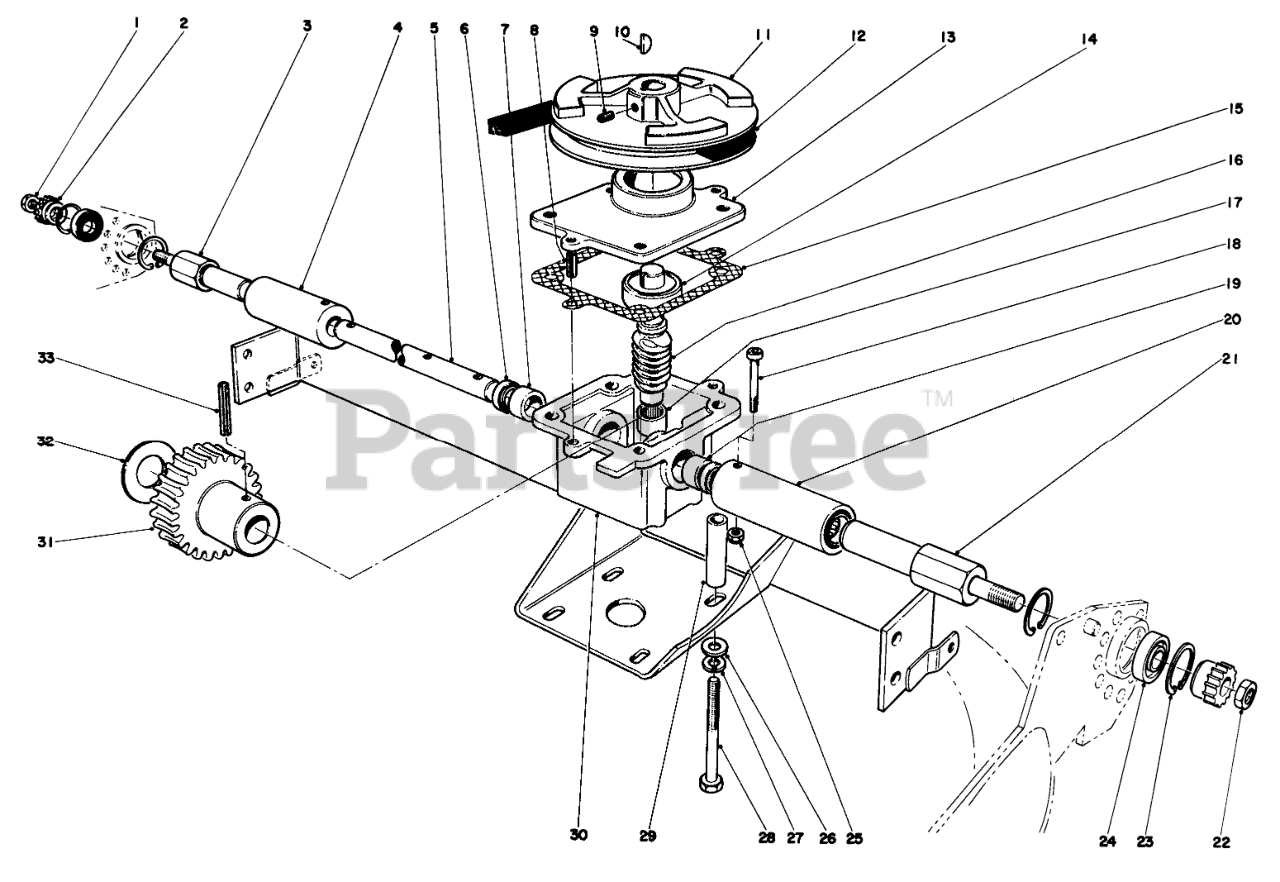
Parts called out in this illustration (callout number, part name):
1	NUT-HJ
2	Pinion Kit
3	OUTPUT SHAFT
4	R/H CLUTCH HSG ASM
5	GEAR BOX SHAFT
6	Seal
7	Bushing
8	3/16 X 1/2 ROLL PIN
9	SCREW-HSH
10	3/32X5/8 WOODRUFF KEY
11	GEAR BOX PULLEY
12	V-BELT
13	Cover Gear Box
14	Bearing
15	GASKET
16	WORM SHAFT
17	.437 NEEDLE BEARING
18	DRIVE SCREW
19	Bushing
20	L/H CLUTCH HSG ASM
21	OUTPUT SHAFT
22	NUT-JAM, LH
23	1-1/8X056 IN SNP RING
24	.375 RPP BALL BEARING
25	NUT-LOCK, NI
26	WASHER-FLAT
27	WASHER-LOCK
28	SCREW-HH
29	GEAR CASE SPACER
30	Gear Case (Incl. Ref. # 6-7 & 17 & 19)
31	WORM GEAR
32	THRUST WASHER
33	5/32 X 7/8 ROLL PIN
